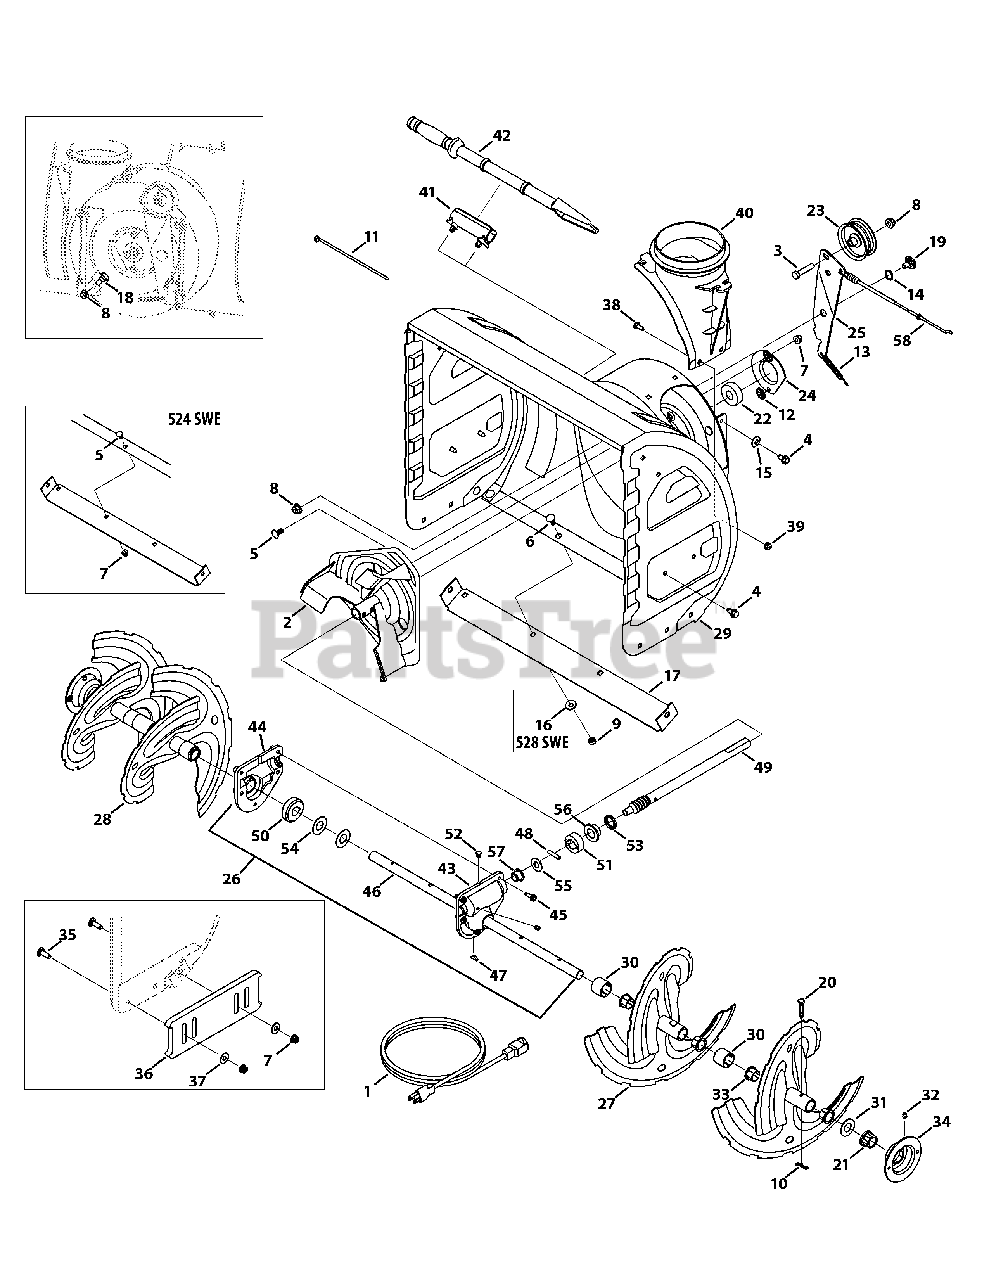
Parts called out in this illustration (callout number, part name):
1	Extension Cord, 3-Prong
2	Impeller Assembly
3	Hex Bolt, 3/8-16 x 1.75
5	Carriage Bolt
6	Carriage Bolt, 5/16-18 x .750
7	Flange Lock Nut, 5/16-18
8	Flange Lock Nut, 3/8-16
9	Hex Nut, 5/16-18
10	Bow Tie Cotter Pin
11	Cable Tie
12	Push Nut
13	Extension Spring
14	Wave Washer
15	Bell Washer
16	Bell Washer, .340 x .872 x .060
17	Stainless Steel, Shave Plate, 28"
17	Stainless Steel, Shave Plate, 24"
18	Shoulder Screw, 3/8-16 x .496 x .336
19	Shoulder Screw, 3/8-16 x .625 x .17
21	Hex Flange Bearing
22	Ball Bearing
23	Flat Idler Pulley
24	Bearing Housing
25	Auger Idler Bracket
26	Gearbox Assembly, Auger, 28"
26	Gearbox Assembly, Auger, 24"
27	Spiral Assembly - LH
28	Spiral Assembly - RH
29	Housing Assembly, Auger, 28"
29	Housing Assembly, Auger, 24"
30	Spacer, .25 x .75 x 1.00
31	Flat Washer, .76 x 1.49 x .06
32	Drive Lube Fitting
33	Flange Bushing
34	Bearing Housing
35	Spacer, Carriage, 5/16-18 x 1.00
36	Deluxe Slide Shoe
37	Washer, Flat, .349 x .879 x .063
38	Carriage Screw, 1/4-20 x 0.75
39	Flange Lock Nut, 1/4-20
40	Chute Adapter
41	Clean-out Tool Mtg. Bracket
42	Clean-Out Tool
43	Reducer Hsg. - LH
44	Reducer Hsg. - RH
45	Taptite Screw, 1/4-20 x 0.75
46	Axle, Auger, 28"
46	Axle, Auger, 24"
47	Hi-Pro Key
49	Worm Shaft
50	Worm Gear, 20T, 28"
50	Worm Gear, 20T, 24"
51	Thrust Collar
54	Flat Washer, .76 x 1.5
55	Flat Washer, .51 x 1.12 x .06
56	Flange Bearing, .75 x 1.00 x .59
57	Flange Bearing, .50 x .75 x .59
58	Auger Clutch Cable
